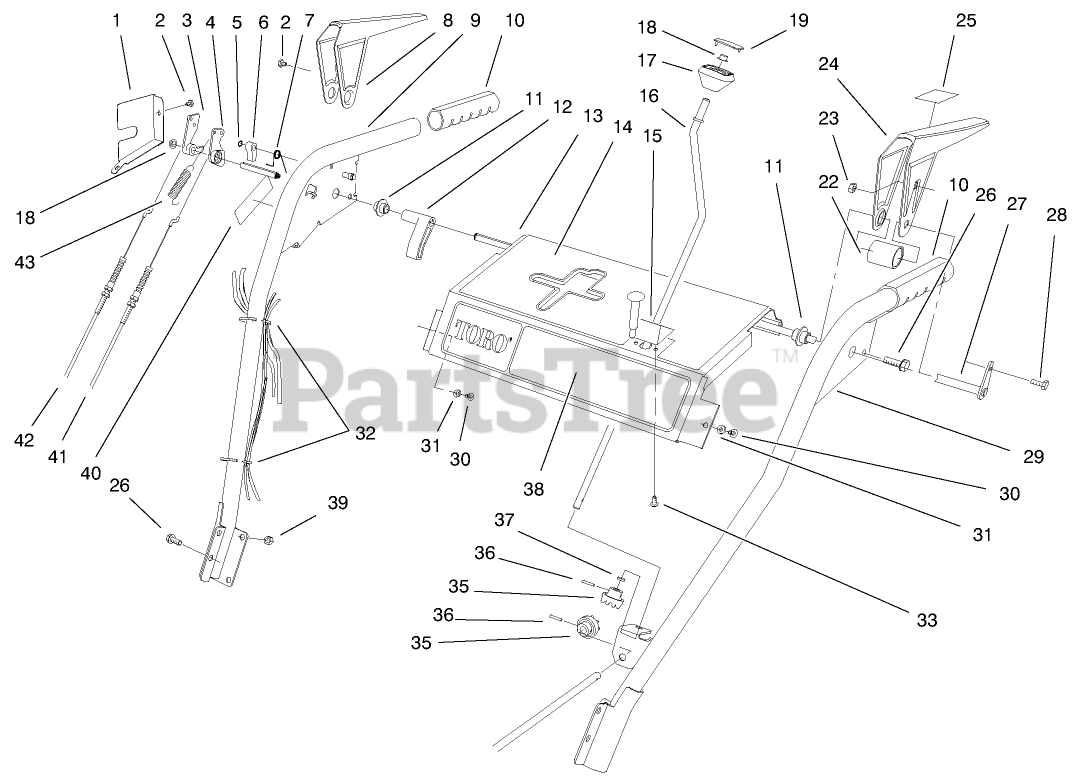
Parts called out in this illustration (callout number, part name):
1	COVER-LOCK, LEVER
2	SCREW-HH
3	TANG-LOCKING
4	CAM-RELEASE
5	E-RING-RETAINER
6	LATCH-LOCKING
7	SPRING-TORSION
8	LEVER-TRACTION, RH
9	RH Handle ASM, 24"-32"
10	GRIP-HANDLE
11	BUSHING-LEVER
12	LEVER-TRIP
13	CONTROL PANEL/DECAL ASM (38542)
13	CONTROL PANEL/DECAL ASM (38543)
14	Decal-Top, Panel (Only On: 38542)
14	Decal-Control (Only On: 38546)
15	PLATE-GUIDE
16	CRANK-ROD, CHUTE
17	KNOB-CONTROL, CHUTE
18	RETAINER-PUSH ON
19	COVER-KNOB
22	SPACER-LEVER, TRACTION
23	NUT-LOCK, NI
24	LEVER-TRACTION, LH
25	Decal-Lever (Only On: 38542)
26	SCREW-HWHTF
27	CROSS ROD ASM
28	SCREW-HWH
29	LH HANDLE ASM
30	SCREW-HWHTF
31	WASHER-FLAT
32	TIE-CABLE
33	SCREW
35	GEAR-UNIVERSAL
36	PIN-SPRING
37	WASHER-RUBBER
38	DECAL-FRONT PANEL (824)
39	NUT-LOCK, NI
40	Decal-Adjustment (Only On: 38546)
40	Decal-Warning (Only On: 38542)
41	CABLE-TRACTION
42	CABLE-IMPELLER
43	SPRING-EXTENSION
